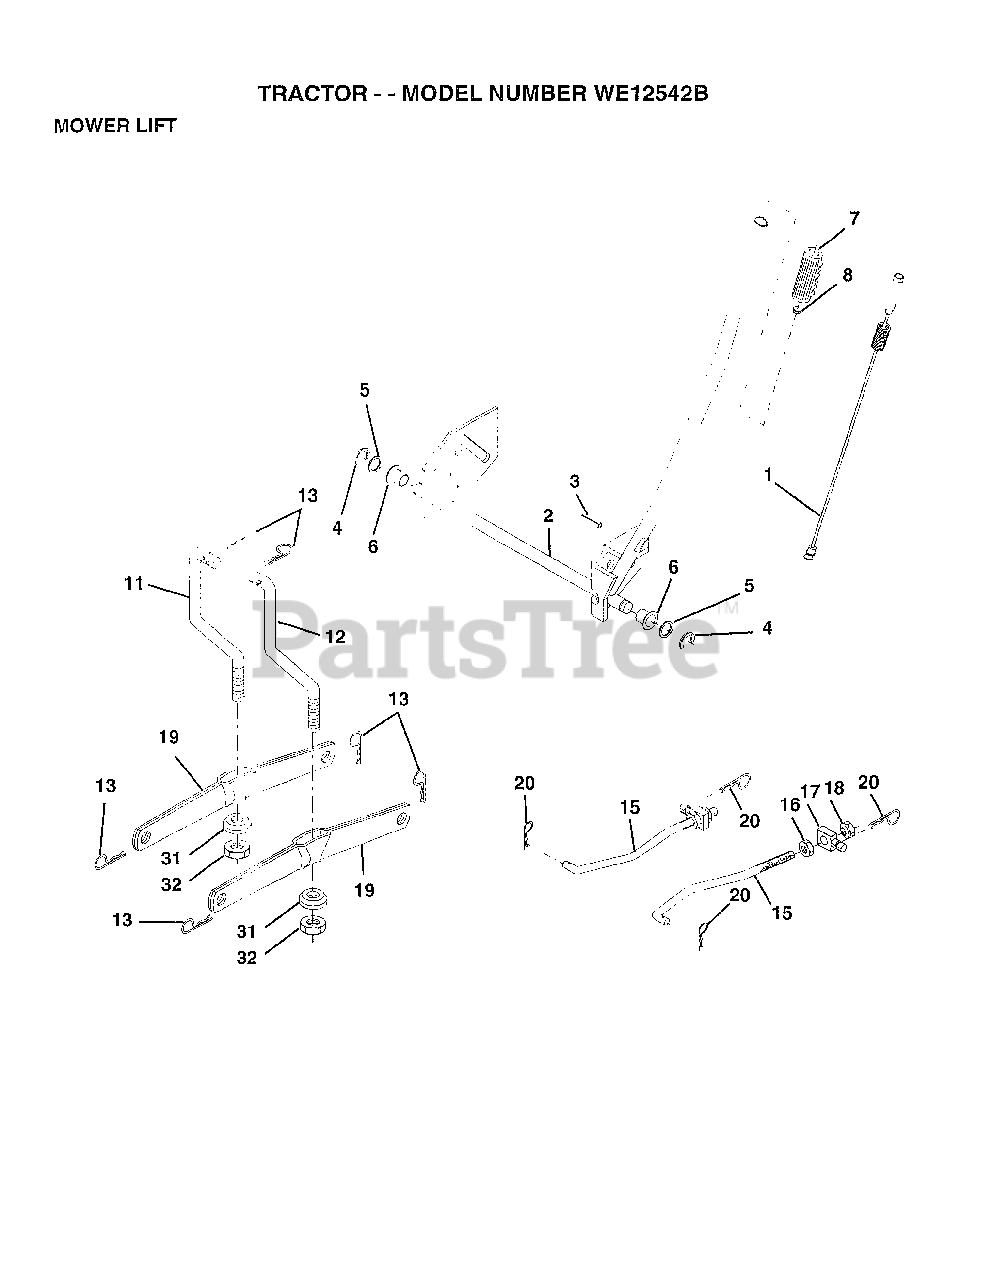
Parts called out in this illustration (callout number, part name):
1	WIRE ASM W.SPRING
2	"SHAFT ASM LIFT,RH"
3	PIN-GROOVE LT
5	WASHER
6	NYLON BEARING
7	GRIP
15	LINK.FRONT
16	NUT
17	TRUNION
18	NUT.LK.W/WSH.1/2.
19	ARM SUSP REAR
20	RETAINER.SPRING
31	BEARING PVT LH
32	NUT.CROWNLOCK.3/8
